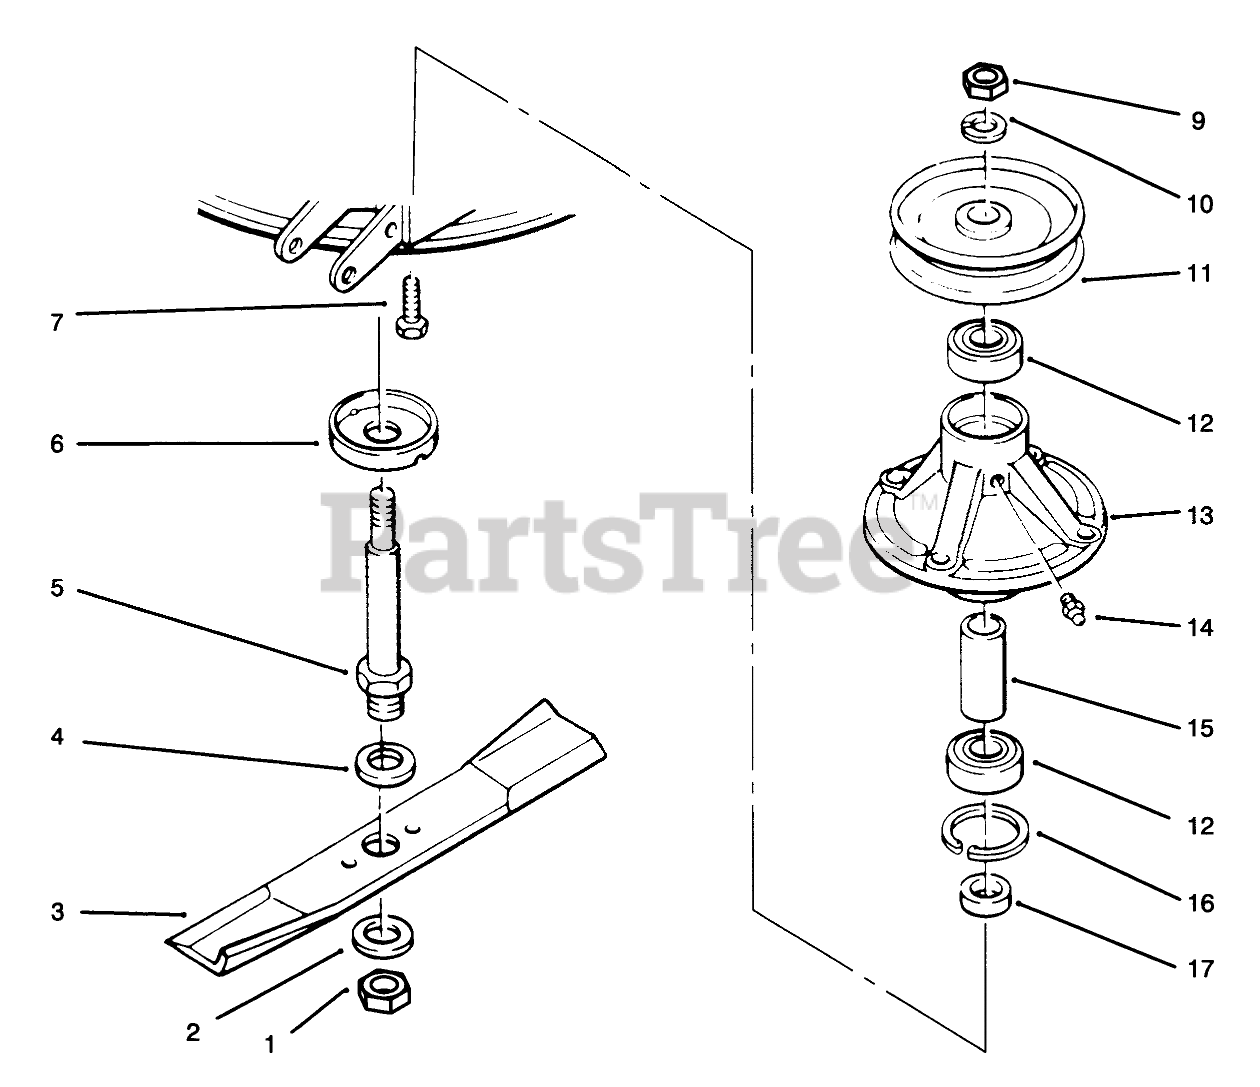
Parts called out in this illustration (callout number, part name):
1	NUT-JAM
2	WASHER-FLAT
3	BLADE 18.75
4	WASHER-FLAT
5	SHAFT SPINDLE
6	CUP-SPINDLE
7	SCREW-HH, LOCK
9	NUT-JAM
10	WASHER-LOCK
11	BLADE PULLEY
12	BEARING-BALL
13	HOUSING SPINDLE
14	ZERK FITTING
16	RING-RETAINING
17	SPACER-BLADE
